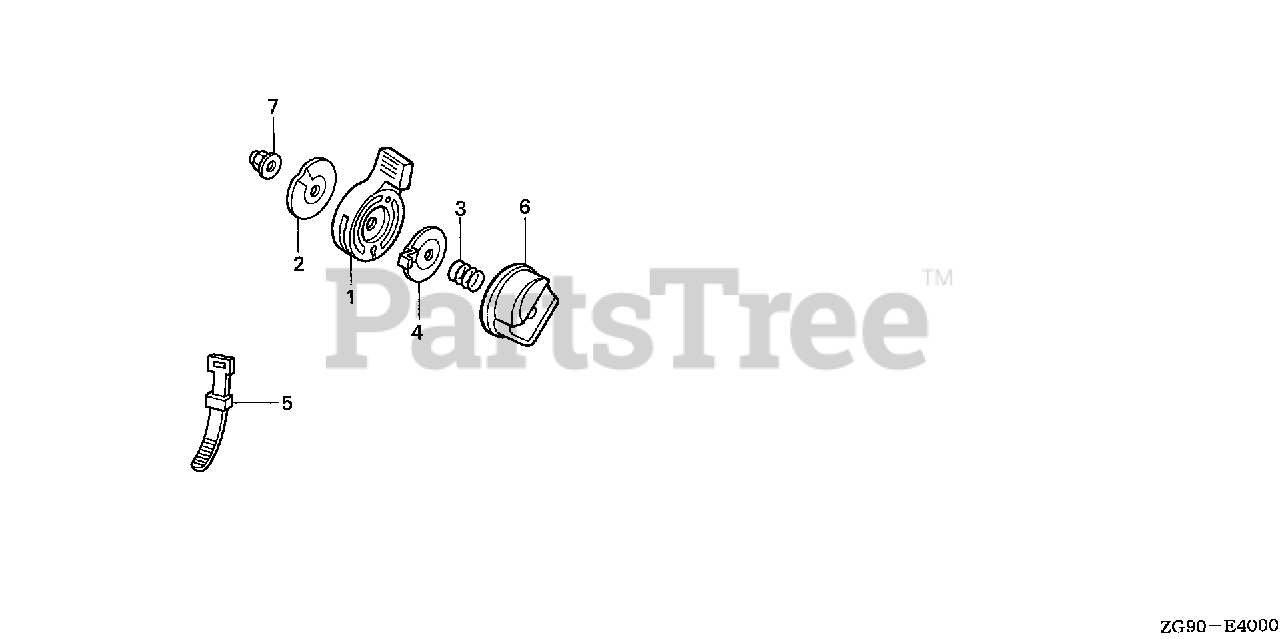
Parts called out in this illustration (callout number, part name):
1	LEVER, THROTTLE
2	PLATE, THROTTLE LEVER
3	SPRING, THROTTLE LEVER
4	SEAT, SPRING
5	BAND B1, WIRE
6	COVER, CONTROL
7	NUT, CAP (6MM)
